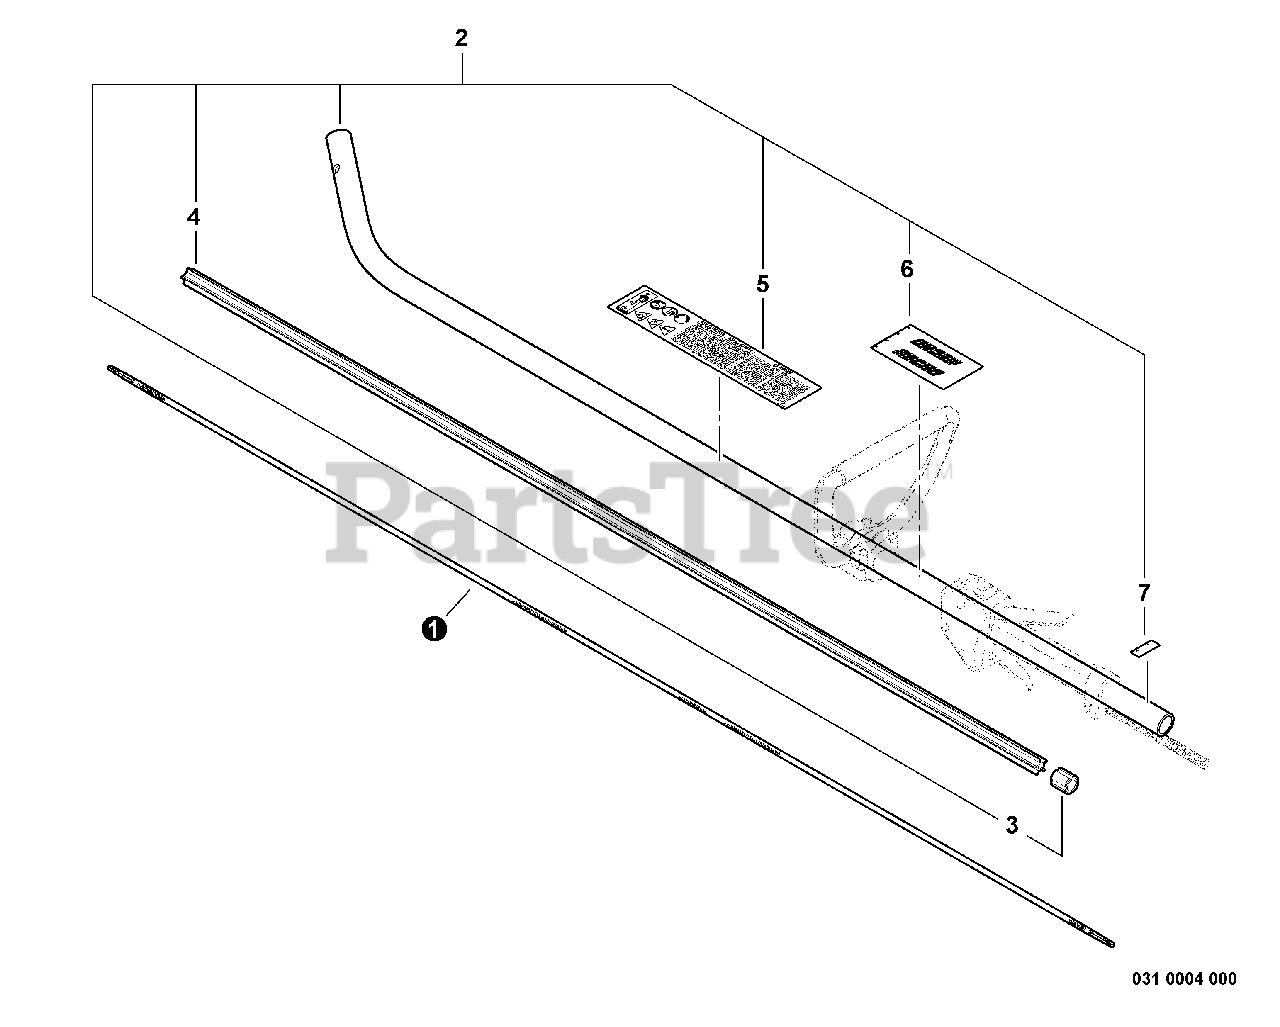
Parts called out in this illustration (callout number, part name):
1	DRIVESHAFT - FLEXIBLE L= 1522
2	MAIN PIPE ASSY
4	LINER, FLEXIBLE 21.6×1420
5	LABEL, CAUTION
6	LABEL, HANDLE LOCATION
7	LABEL - ALIGNMENT
